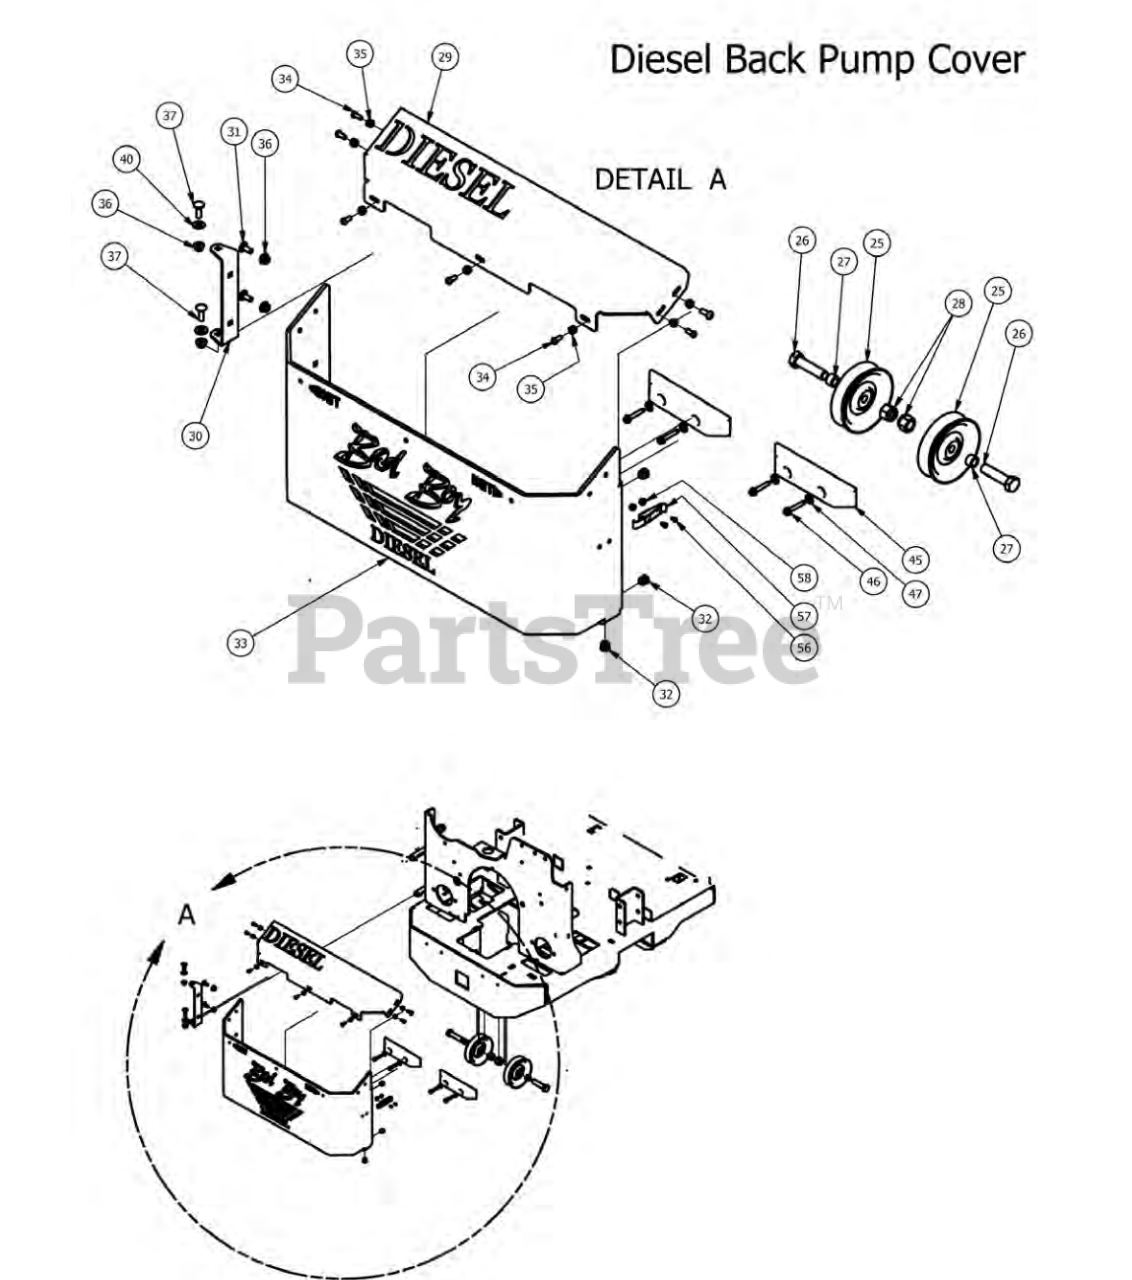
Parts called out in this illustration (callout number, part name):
1	5/8"x10" Hex Bolt (Grade8)
2	5/8" Nylock (1/2 Jam)
3	1/2" Washer (Grade 8)
4	1/2" Lock Washer
5	1/2" x 1" Hex Bolt
6	5/8 Std NC Nylock Nut
7	60" Suspension Kit Wheel Motor
8	Vibration Mount-Blue Dot
9	Isolator Band Clamp
10	5/16" x 1" Carriage Bolt
11	5/16" Nylock Flange Nut
12	1/8 x 2-1/4 Cotter Pins Zinc
13	Woodruff Key
14	1/2" Flange Nut
15	1/2" x 2 1/2" Hex Bolt
16	18cc Parker Wheel Motor-Right
17	1" Castle Nut for Wheel Motor
18	HGB-Dexx-x5-Hub
19	Brake- Right- HGB-BEH-XX
20	5/16-18 x 3/4 Socket C/S
21	45 Degree Wheel Motor Fitting -6802-10-10
22	Brake-Left-HGB-BEHC-XX
23	18cc Parker Wheel Motor- Left
24	Pump Plate Diesel
25	5 V Idler Pulley - BCVI-81
26	5/8" x 2 1/2" Hex Bolt
27	5/8" x 1/" Collar Spacer
28	5/8 Std NC Nylock Nut
29	Diesel Back Pump Cover 2008 and up
30	Pump Cover Hinge
31	5/16-18 x 3/4 Carriage Bolt
32	5/8 Round Insert
33	Diesel Back Pump Cover 2008
34	1/4" x 5/8" Buttonhead Bolt
35	1/4" Nylock Nut
36	5/16" Flange Nut
37	5/16" x 1" Carriage Bolt
38	.360 ID Plastic Washer
39	Diesel Hood 3 Cyl
40	5/16" Knob
41	5/16-18 Nylon Insert Locknut
42	5/16" x 1" Bolt
43	5/16" x 1 1/4" Carriage Bolt
44	5/16" Flange Nut
45	8" Rubber Bumper
46	1/4" x 1 1/2" Self Tapping Screw
47	1/4" Flat Washer
48	26" Hose Assembly with Adaptors
49	72" Suspension Kit Wheel Motor
50	26" Hose Only
51	Diesel Hood 4cyl
52	26 x 12.00-12 Tire and Orange Wheel Assembly
53	12 x 10.5 Wheel AOS Rear
54	26 x 12.00-12 Tire
55	Acorn Lug Nut
56	1024 X 5/8" Buttonhead Bolt
57	Steel Pump Cover Latch
58	#10 Nylock Nut
59	1/2-13 x 1-1/4 Hex Bolt Only on 60° Suspension Kit wheel Motor
